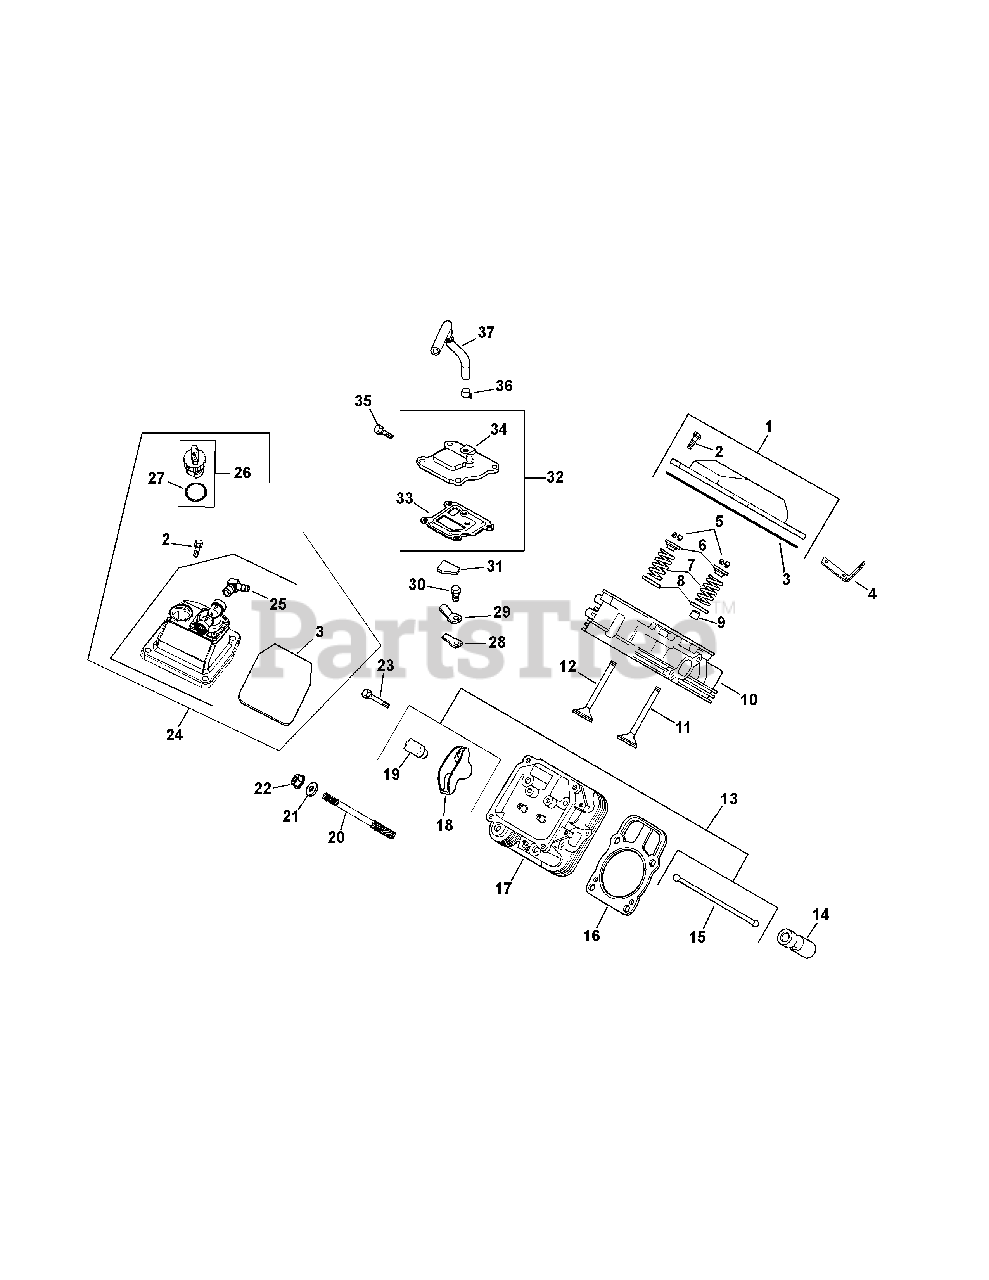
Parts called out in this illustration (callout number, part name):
1	KIT, VALVE COVER-PLAIN
2	SCREW, FLG M6X1.0X30
3	O-RING, VALVE COVER
4	STRAP, LIFTING
5	KIT, RETAINER
6	CAP, VALVE SPRING
7	SPRING, VALVE
8	RETAINER, SPRING
9	SEAL, VALVE STEM
10	KIT, #1 CYLINDER HEAD ASSEMBLY
11	VALVE, INTAKE (STD)
11	VALVE, INTAKE (.25)
12	VALVE, EXHAUST (STD)
12	VALVE, EXHAUST (.25)
13	KIT, VALVE TRAIN
14	LIFTER, VALVE HYDRAULIC
16	KIT, CYL HEAD GASKE T (C17-22)
17	KIT, #2 CYLINDER HEAD ASSEMBLY
19	PIVOT, ROCKER ARM
20	SCREW-HEX, FLG, M10 X 1.5 X 90
21	Not used in this application
22	Not used in this application
23	SCREW, FLG M6X1.0X34
24	KIT, VALVE COVER-FUEL PUMP
25	KIT, 90 DEG. FITTING
26	CAP ASSY, OIL FILL (YELLOW)
28	RETAINER, REED
29	REED, BREATHER
30	SCREW, FLG THD FRM M5X.8X10
31	FILTER, BREATHER
32	KIT, BREATHER ASSEMBLY
33	GASKET, BREATHER
34	KIT, BREATHER ASSEMBLY
35	SCREW, FLG THD FRM M6X1.0X20
36	CLAMP, HOSE 1/2''
37	BREATHER HOSE
